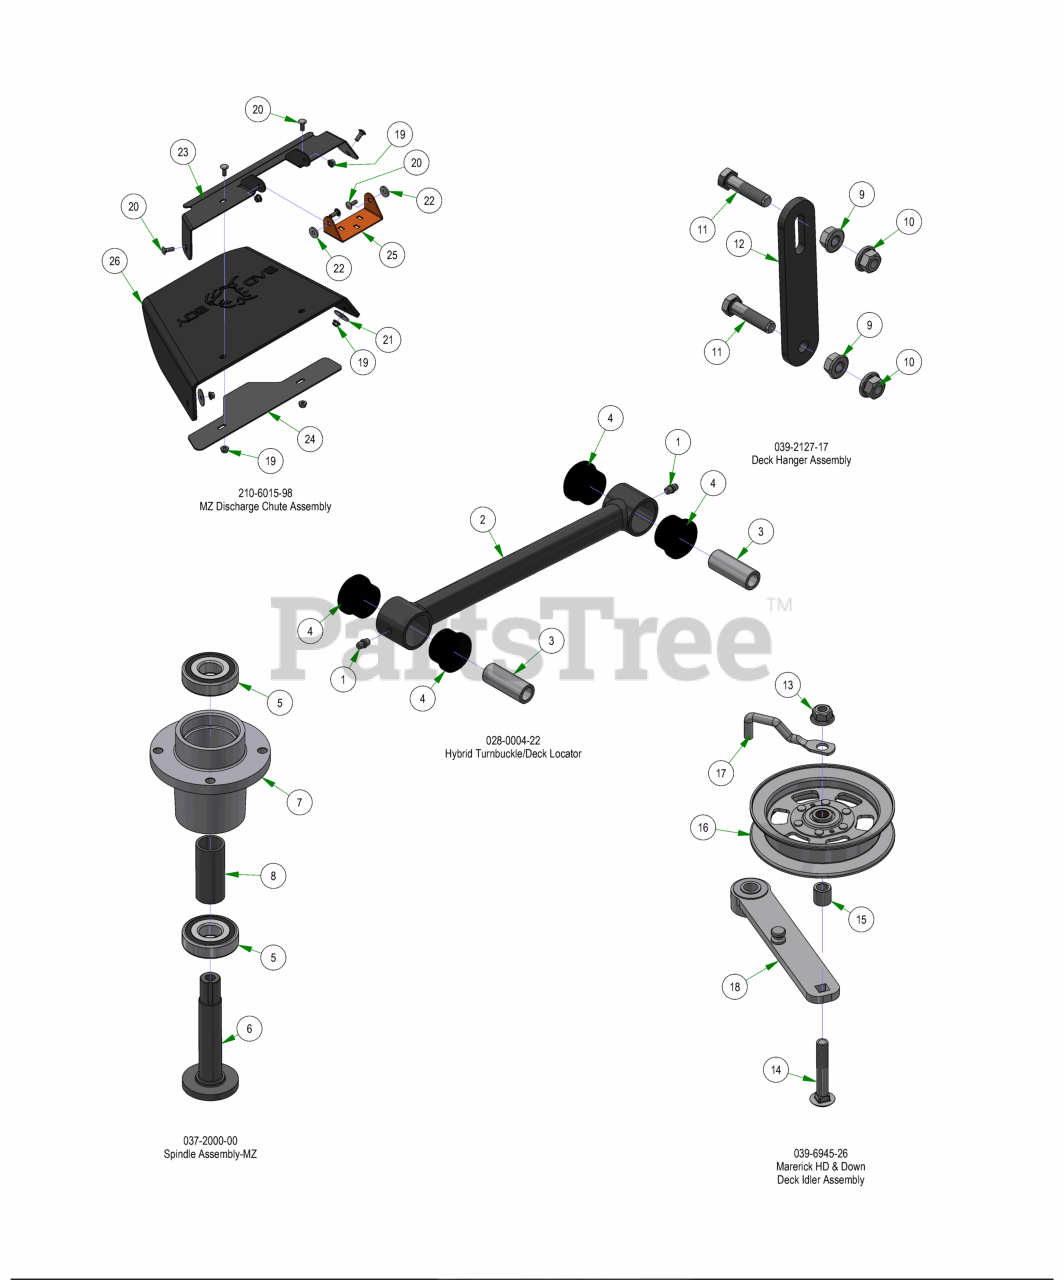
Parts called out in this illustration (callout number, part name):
1	1/4-28 Grease Fitting
2	2022 Isolator Turnbuckle Body
3	2018 Maverick Bushing Sleeve
4	2018 Maverick Bushing
5	Spindle Bearing
6	Spindle Shaft
7	Spindle Housing
8	Spindle Spacer-Component
9	3/8-16 HEX SERRATED FLANGE NUT HARD/ZINC
10	3/8-16 NYLON INSERT FLANGE LOCKNUT (GR.F) ZINC
11	3/8-16 X 1-1/2 HEX CAP SCREW (GR.5) ZINC
12	2017 MZ/ZT Deck Hanger
13	1/2-13 NYLON INSERT FLANGE LOCKNUT ZINC
14	1/2-13 x 3 Carriage Bolt Grade 5
15	.51 ID X .75 OD X .75 LGTH SOLID SPACER ZINC
16	5" Idler Pully
17	2025 R-Series Belt Retainer
18	2025 Tensioner Arm With Bearings
19	5/16-18 NYLON INSERT FLANGE LOCKNUT ZINC
20	5/16-18 X 7/8 CARRIAGE BOLT ZINC
21	5/16 FENDER WASHER (1-1/2 OD) ZINC
22	.360 ID X .983 OD X .120 THICK FLAT WASHER NYLON
23	Discharge Chute Bracket 48 MZ (Upper)
24	2017 MZ Discharge Chute Bracket-Lower
25	Chute Hanger 48 MZ
26	Rubber Discharge Chute MZ (Component)
